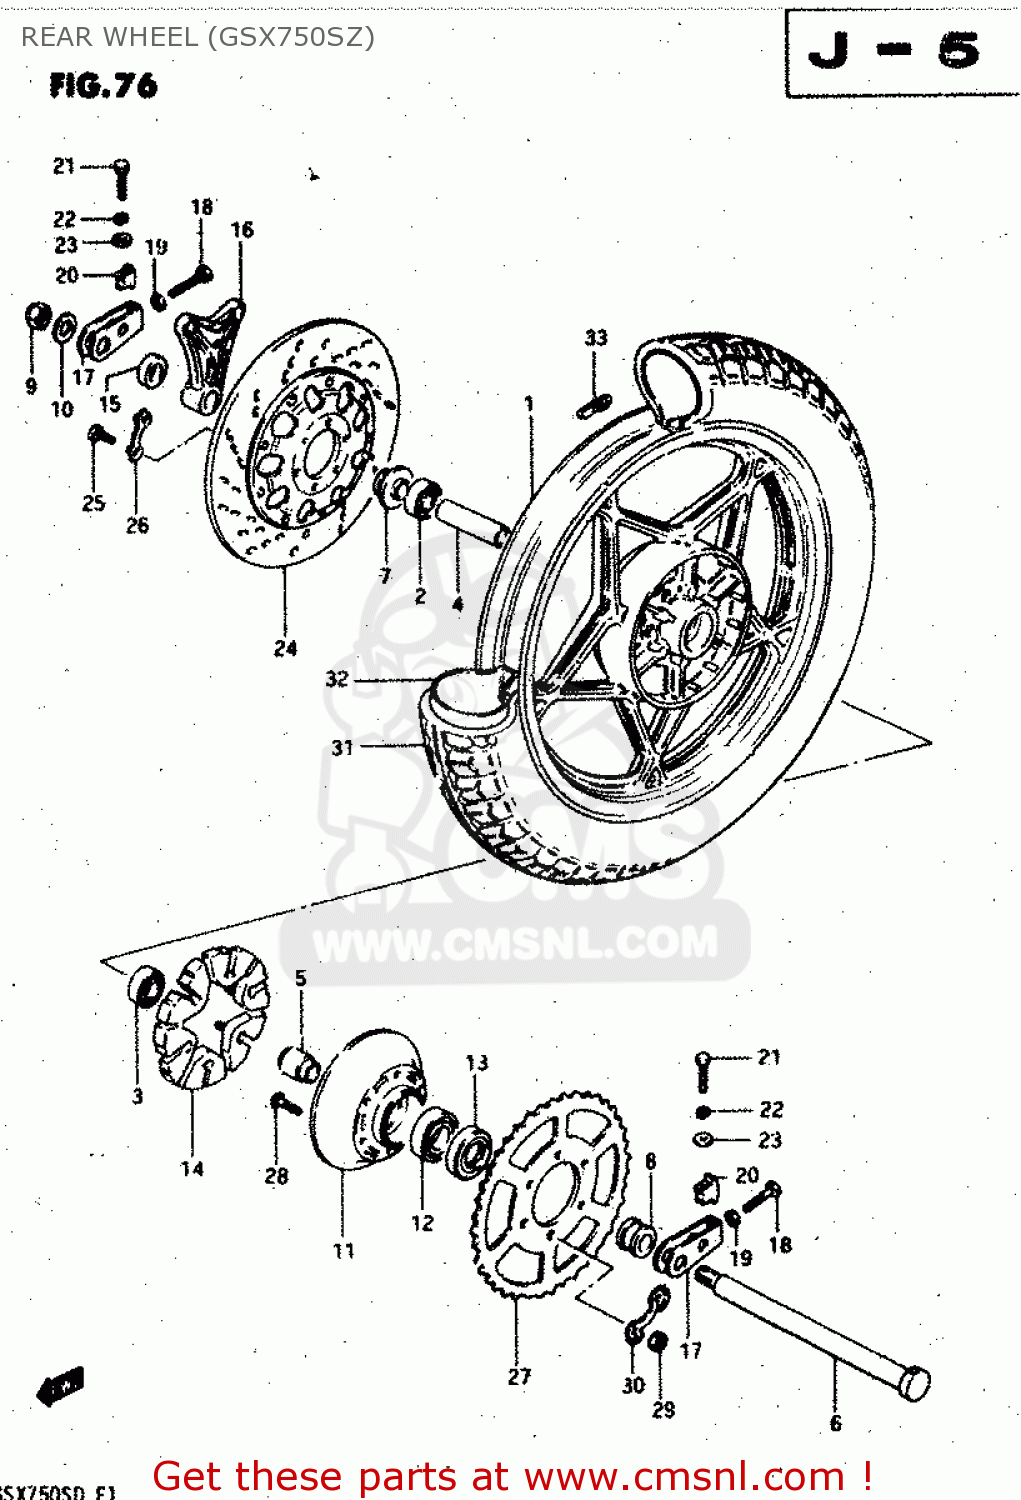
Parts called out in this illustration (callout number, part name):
1	CASTING WHEEL,REAR 2.15
2	BEARING WHEEL REAR(20X47X14)
3	BEARING, LH
4	SPACER,REAR HUB BEARING
5	SPACER,REAR HUB BEARING
6	AXLE,REAR
7	SPACER,REAR AXLE
8	SPACER(20X33X28.3)
9	NUT
10	WASHER(19X34X4)
11	DRUM,REAR SPROCKET MOUNT
12	BEARING
13	SEAL,OIL(33X62X7)
14	ABSORBER,REAR HUB SHOCK
15	SPACER (20X38X17)
16	BRACKET,RR,CALIPER
17	ADJUSTER,CHAIN
18	BOLT
19	NUT
20	SUPPORTER,CHAIN ADJUST
21	BOLT
22	LOCK WASHER
23	WASHER
24	DISC,RR BRAKE
25	BOLT(8X30)
26	WASHER
27	SPROCKET,RR
28	BOLT
29	NUT
30	WASHER
31	TIRE 4.00-H18
32	TUBE,INNER
33	BALANCER,WHEEL
